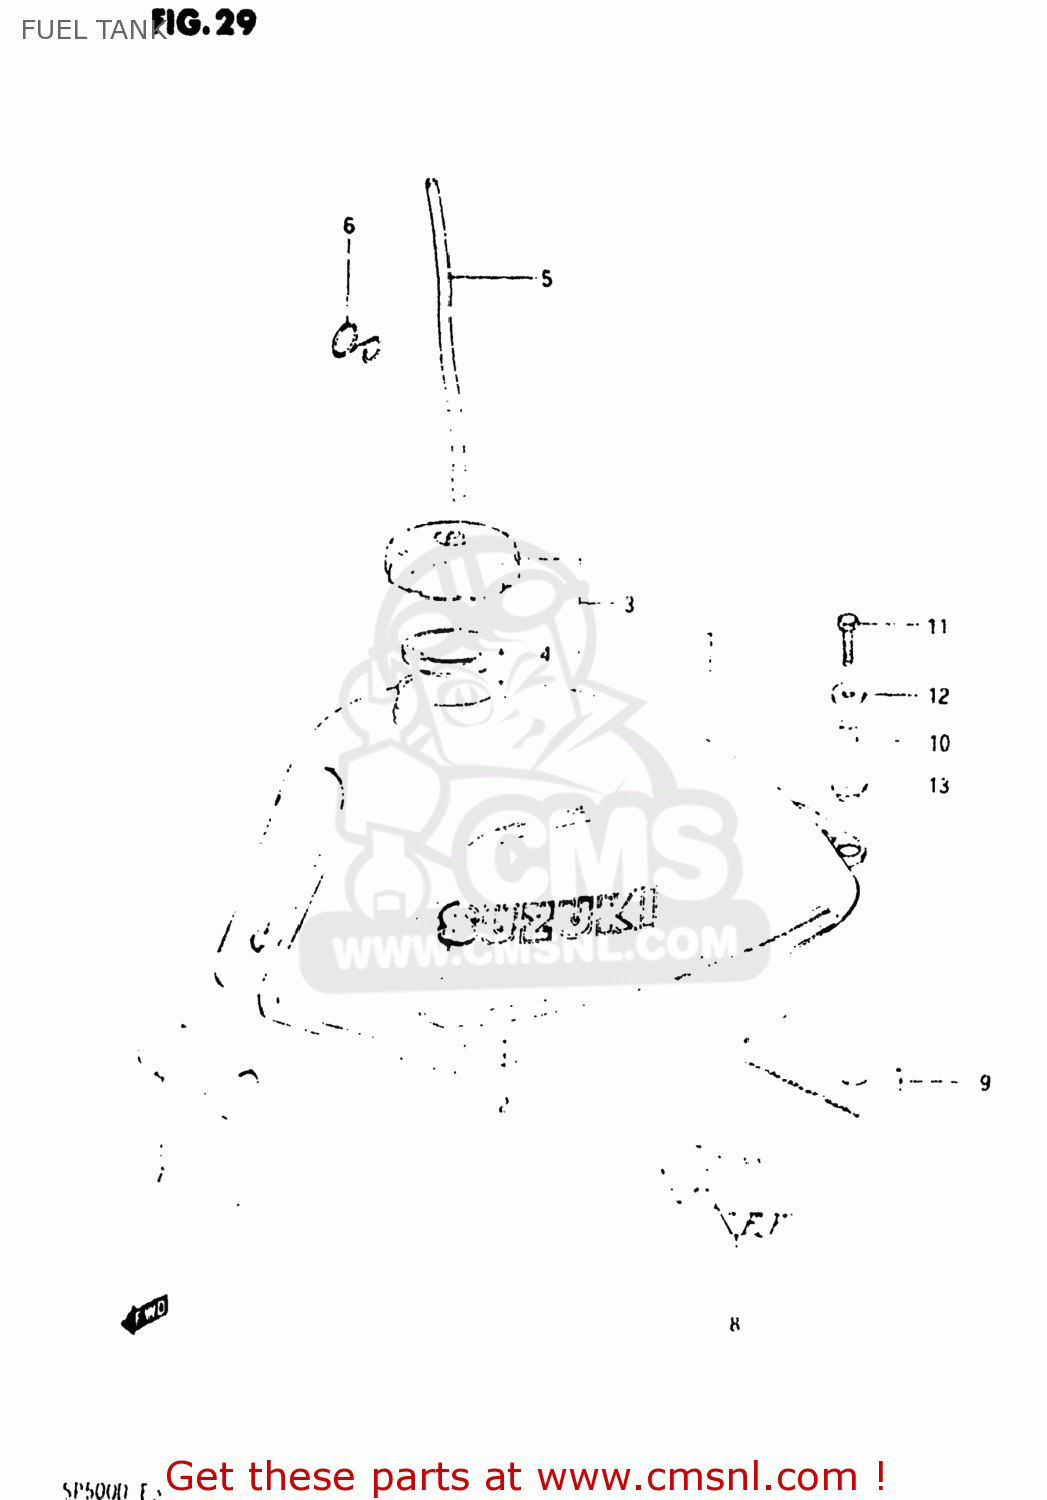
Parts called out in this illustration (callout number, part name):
1	TANK ASSEMBLY,FUEL
2	TAPE SET,FUEL TANK
3	CAP,FUEL TANK
4	GASKET,FUEL TANK CAP (NAS)
5	HOSE,FUEL
6	GUIDE,CABLE
7	CUSHION
8	CUSHION,FUEL TANK UPR FR
9	CUSHION,FUEL TANK,REAR
10	SPACER (6.5X10.5X29)
11	BOLT 6X40
12	WASHER (6.5X24X1.6)
13	CUSHION
